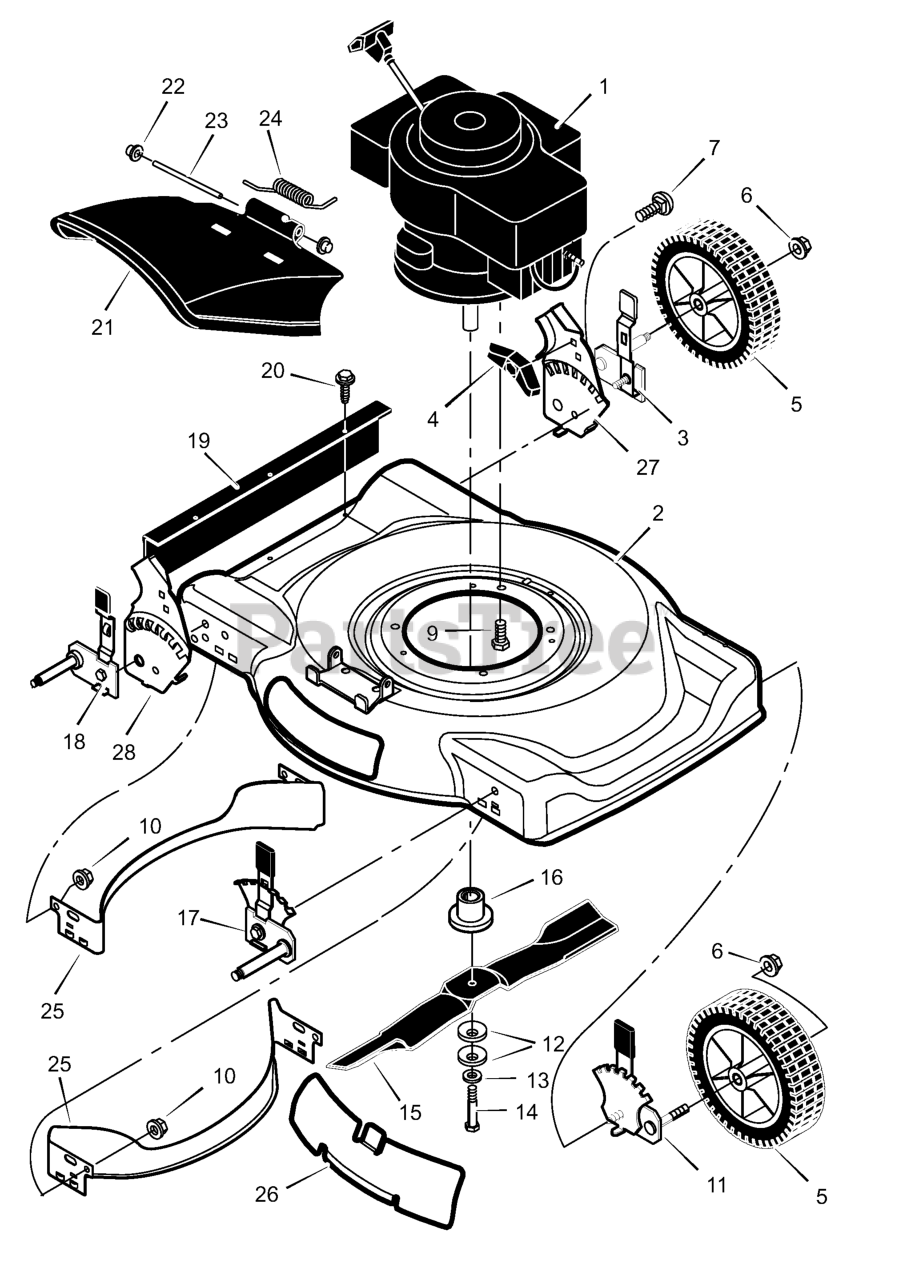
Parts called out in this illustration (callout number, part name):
1	Engine *
2	Housing
3	Height Adjuster, Left Rear
5	Wheel and Tire
6	Locknut, Flange
7	Bolt, Carriage
9	Bolt, Engine
10	Nut
11	Height Adjuster, Left Front
12	Washer, Belleville
14	Bolt, Hex
15	Blade, Mulcher
16	Adapter, Blade
17	Height Adjuster, Right Front
18	Height Adjuster, Right Rear
19	Guard, Rear
21	Deflector, Chute
22	Push-On Cap
23	Pin, Pivot
25	Baffle -
26	Plate, Mulcher
27	Bracket, Left Handle
28	Bracket, Right Handle
